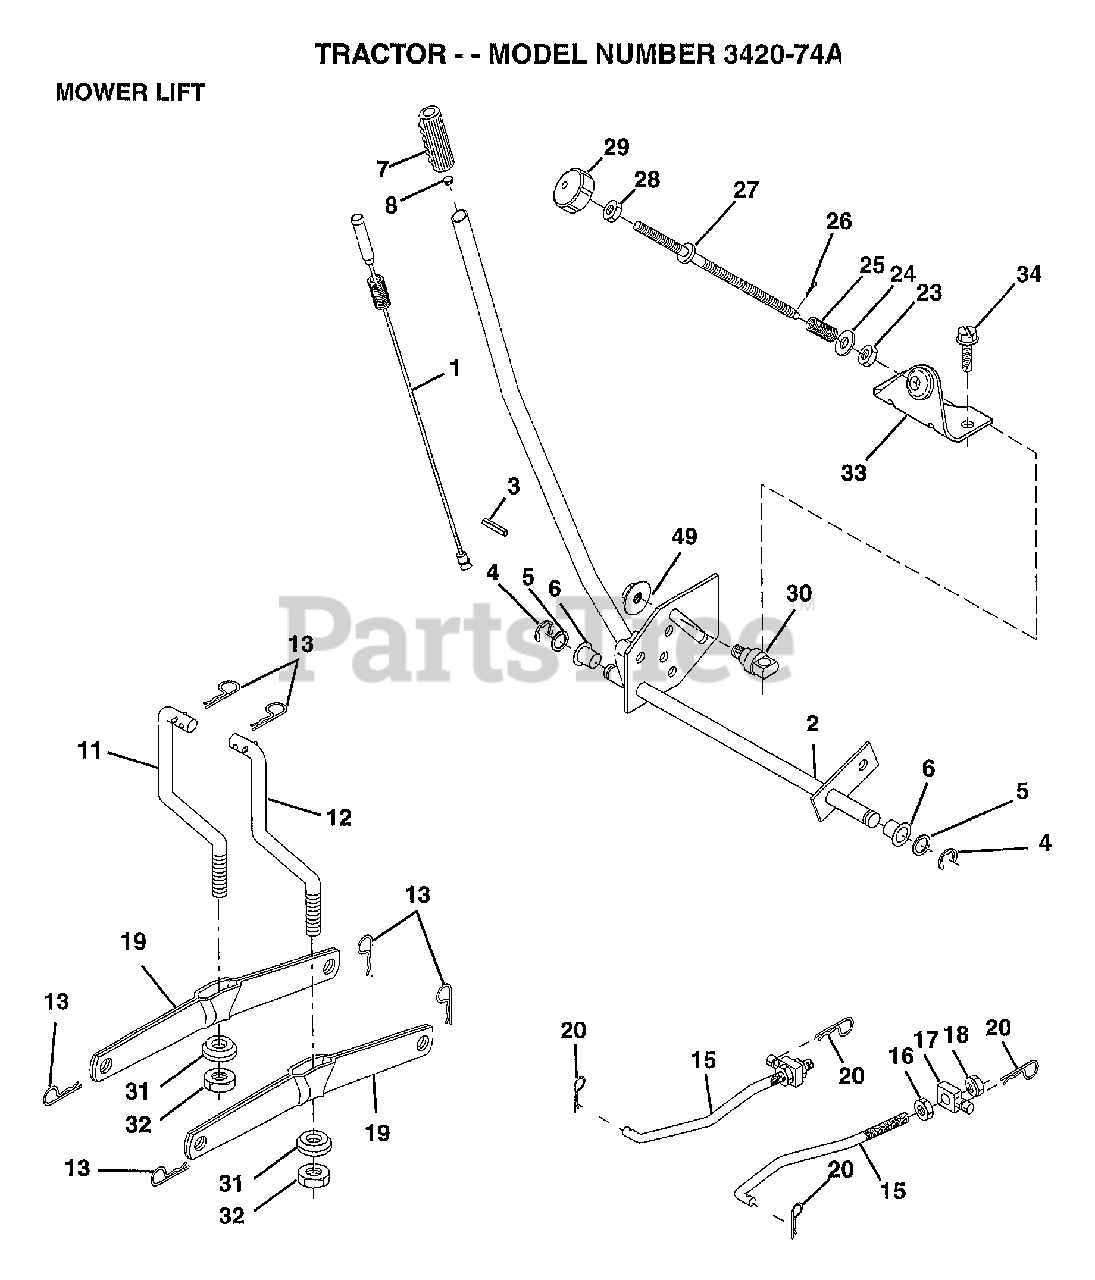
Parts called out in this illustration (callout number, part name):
1	WIRE ASM W.SPRING
2	"SHAFT ASM LIFT,LH"
3	PIN GROOVE
5	WASHER
6	NYLON BEARING
7	GRIP
15	LINK.FRONT
16	NUT
17	TRUNION
18	NUT.LK.W/WSH.1/2.
19	ARM SUSP REAR
20	RETAINER.SPRING
23	NUT T
24	WASHER
25	SPRING.COMP.INF.H
27	ROD.ADJ.LIFT
28	NUT
29	KNOB INF 3/8-16
30	TRUNNION
31	BEARING PVT LH
32	NUT.CROWNLOCK.3/8
49	NUT.HXFLG.LOCK.
50	NUT PUSH M
